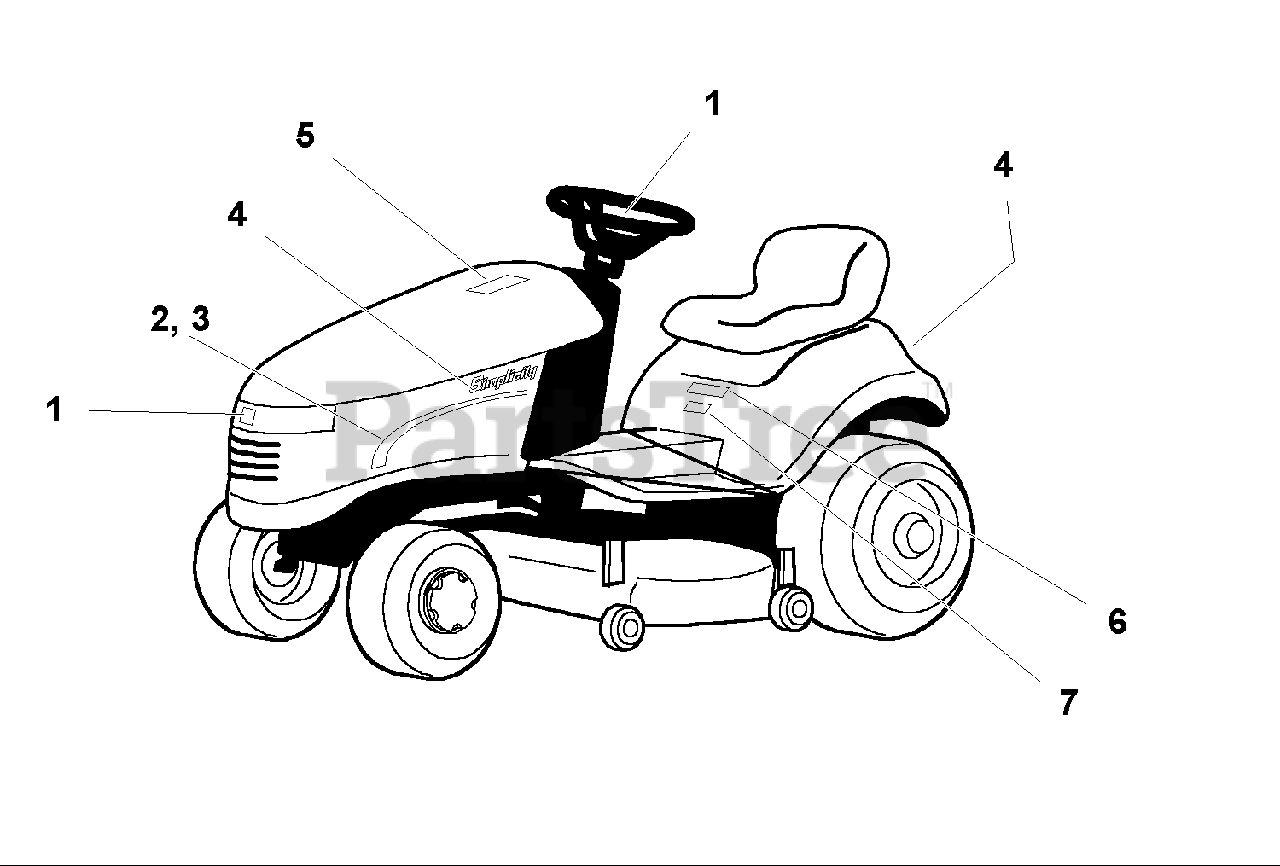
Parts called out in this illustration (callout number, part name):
1	DECAL, Simplicity Icon
2	DECAL, Simplicity Stripe RH
3	DECAL, SimplicityStripe LH
4	DECAL, Simplicity
5	DECAL, Touch Up Paint
6	DECAL, Regent, Silver & Blue
7	DECAL, 16 HP
